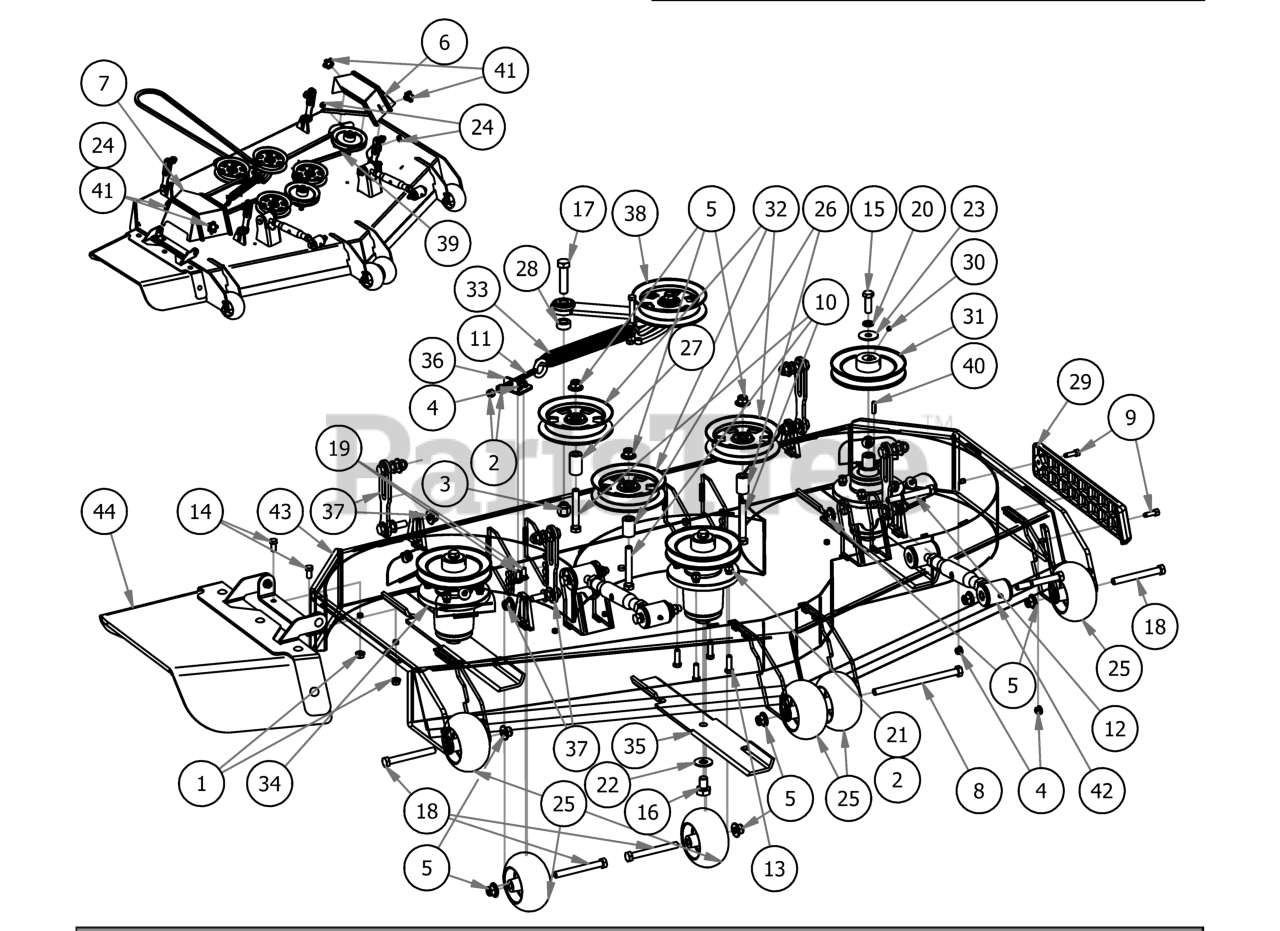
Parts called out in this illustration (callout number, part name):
1	3/8" Flange Nut
2	3/8" Hex Nut
3	5/8 Std NC Nylock Nut
4	5/16" Nylon Flange Nut
5	1/2-13 Nylon Flange Nut
6	2019 61" Outlaw Gen2 Pulley Cover Left
7	2019 61" Outlaw Gen2 Pulley Cover Right
8	1/2-13 x 8 Hex Bolt Grade 5
9	5/16-18 x 1 GR 5 Hex Bolt Zinc
10	1/2 x 3 1/2 Flange Bolt Grade 8
11	4" 3/8-16 Eye Bolt
12	1/2" x 4" Bolt (Grade 8)
13	3/8" x 1 1/4" Hex Bolt
14	3/8" x 3/4" Hex Bolt
15	1/2"-20 x 1 1/2 - Grade 5 Fine Thread Bolt
16	5/8" x 1 1/2" Grade 8 Hex Bolt (Fine)
17	5/8" x 2 1/2" Grade 5 Hex Bolt (Coarse)
18	1/2" x 4 1/2" Bolt
19	5/16" x 7/8" Carriage Bolt
20	1/2" Lock Washer
21	3/8" Lock Washer
22	5/8'' Flat Washer
23	1/2" Belleville Washer
24	.360 ID Plastic Washer-Black
25	2019 Deck Wheel
26	.502 ID X .750 OD X 1.500 Long Spacer
27	1 3/4" Pulley Spacer
28	5/8" x 1/" Collar W/One Set Screw
29	REVISED TRIM BUMPER_20180226
30	5/16 Set Screw
31	6 1/4" Drive Pulley
32	5-3/4 Idler Pulley
33	2019 Outlaw Gen2 Deck Spring
34	OUTLAW SPINDLE ASSEMBLY
35	61 inch Fusion Blade
36	2019 Deck Eye Bolt Tab
37	Deck Hangar Assembly
38	2019 Renegade Deck Idler
39	Deck Belt for 61" Renegade
40	1/4" x 1" Key
41	5/16" Knob
42	Turnbuckle
43	2019 Sloped 61" Deck
44	2019 Outlaw Gen2 Chute Assembly
